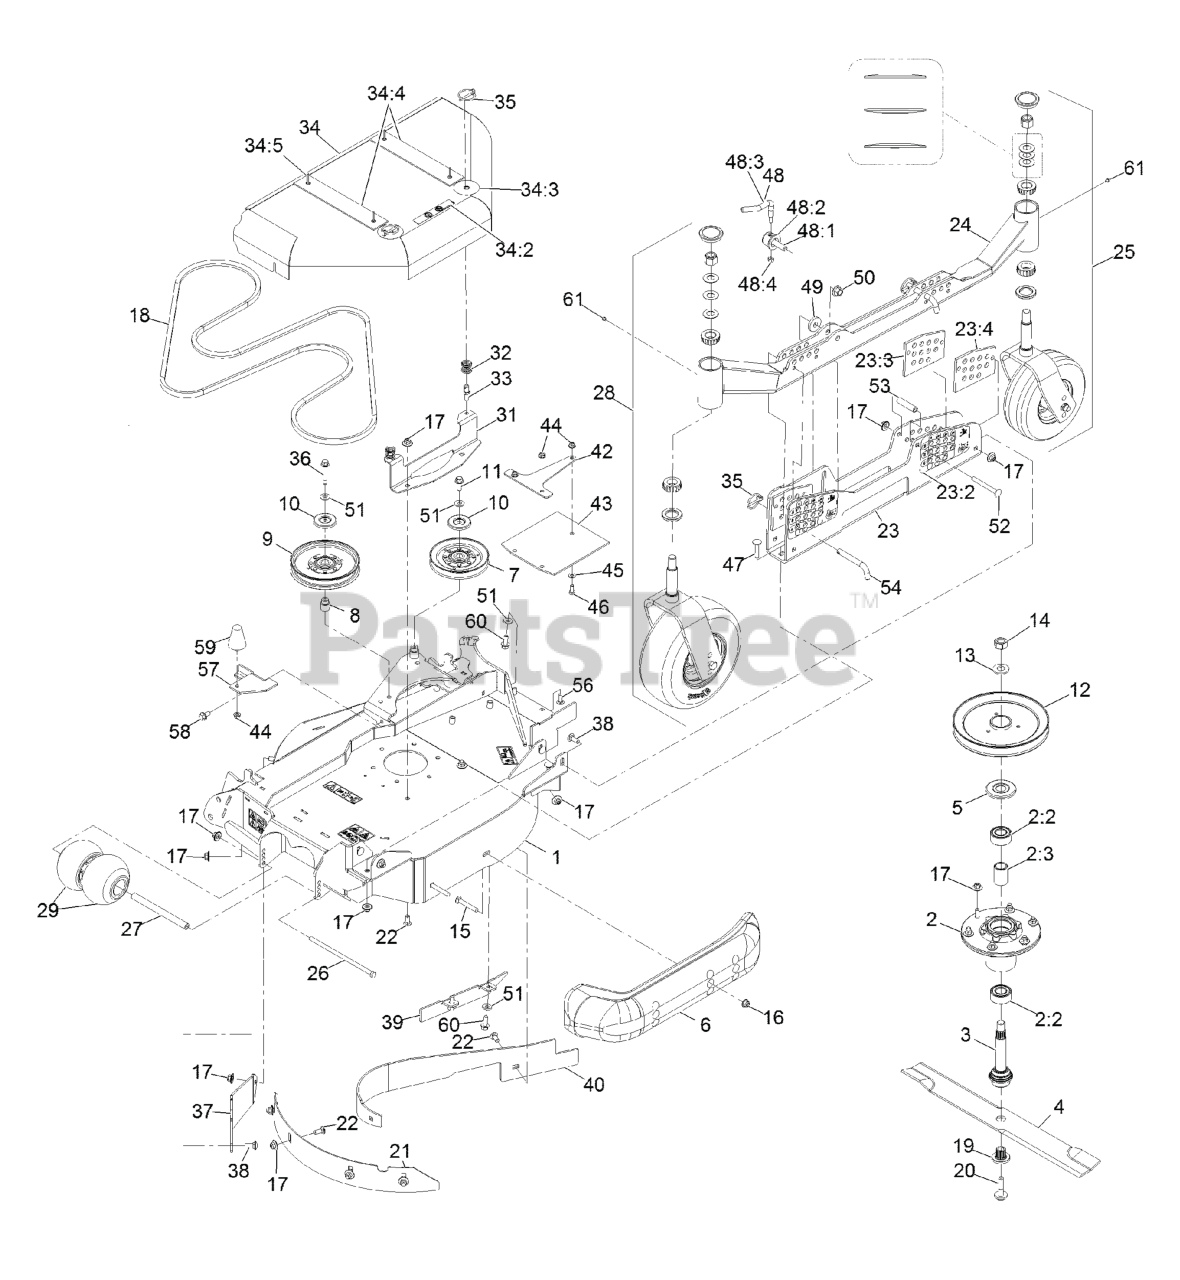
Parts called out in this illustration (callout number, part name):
1	ASM-DECK, LH WING 96/120
2	ASM-CUTTER HSG
2:2	BEARING-3205 TRASHGUARD
2:3	SPACER-BEARING
3	ASM-SPINDLE AND SEAL
5	GUARD-BEARING, TOP
6	SKID-BUMPER, DECK
7	IDLER-V
8	BUSHING-IDLER
9	IDLER-PULLEY
10	SHIELD-DUST
11	SCREW-HHF 3/8-16 X 1
12	SHEAVE-SINGLE 96RD
14	NUT-HEX
15	SCREW-CARR
16	NUT-HF, NI
17	Nut-Nyloc 3/8-16 Flg
19	BUSHING,SPLINED
20	SCREW,SEMS 1/2-20 X 2.19
21	BAFFLE-DEPTH, LH
22	BOLT-CARR
23	LH HOC CHANNEL ASM
23:2	DECAL-HEIGHT OF CUT-LH
23:3	PLATE-GUIDE, HOC (LH)
23:4	PLATE-GUIDE, HOC (RH)
24	TUBE-HOC, LH
25	Caster/Wheel ASM
26	SCREW-HH
27	SPACER-WHEEL
29	ROLLER-SCALP, ANTI
31	BRACKET-SHIELD MOUNT, OUT
33	PIN-SPRING
34	ASM-Wing Shield LH
34:2	DECAL-NO STEP
34:3	DECAL-SCRATCH COVER
34:4	Plate-Uhmw 2"
34:5	Rivet-Pop
35	PIN-LYNCH
36	SCREW-HHF
37	PLATE-FILL, LH DECK
38	BOLT-CARR
39	Fin-Baffle, Discharge Wing (LH)
40	BAFFLE-DOGLEG, CENTER (RH
42	SUPPORT-FLAP, LH
43	GUARD-TIRE, LH
44	NUT-HF, NI
45	WASHER-PLAIN
46	SCREW-HH
47	SCREW-CARR
48	LEVER ASM
48:1	SCREW-LOCK
48:2	CAP-LOCK
48:4	NUT-LOCK, NI
50	Nut-Lock 1/2-13
51	WASHER-BELLEVILLE
52	SCREW-CARR
54	PIN-HOC
56	BOLT-CARR
57	BRACKET-COVER RETAINER
58	SCREW-HWH
59	BUMPER-RUBBER
60	SCREW-HHF
